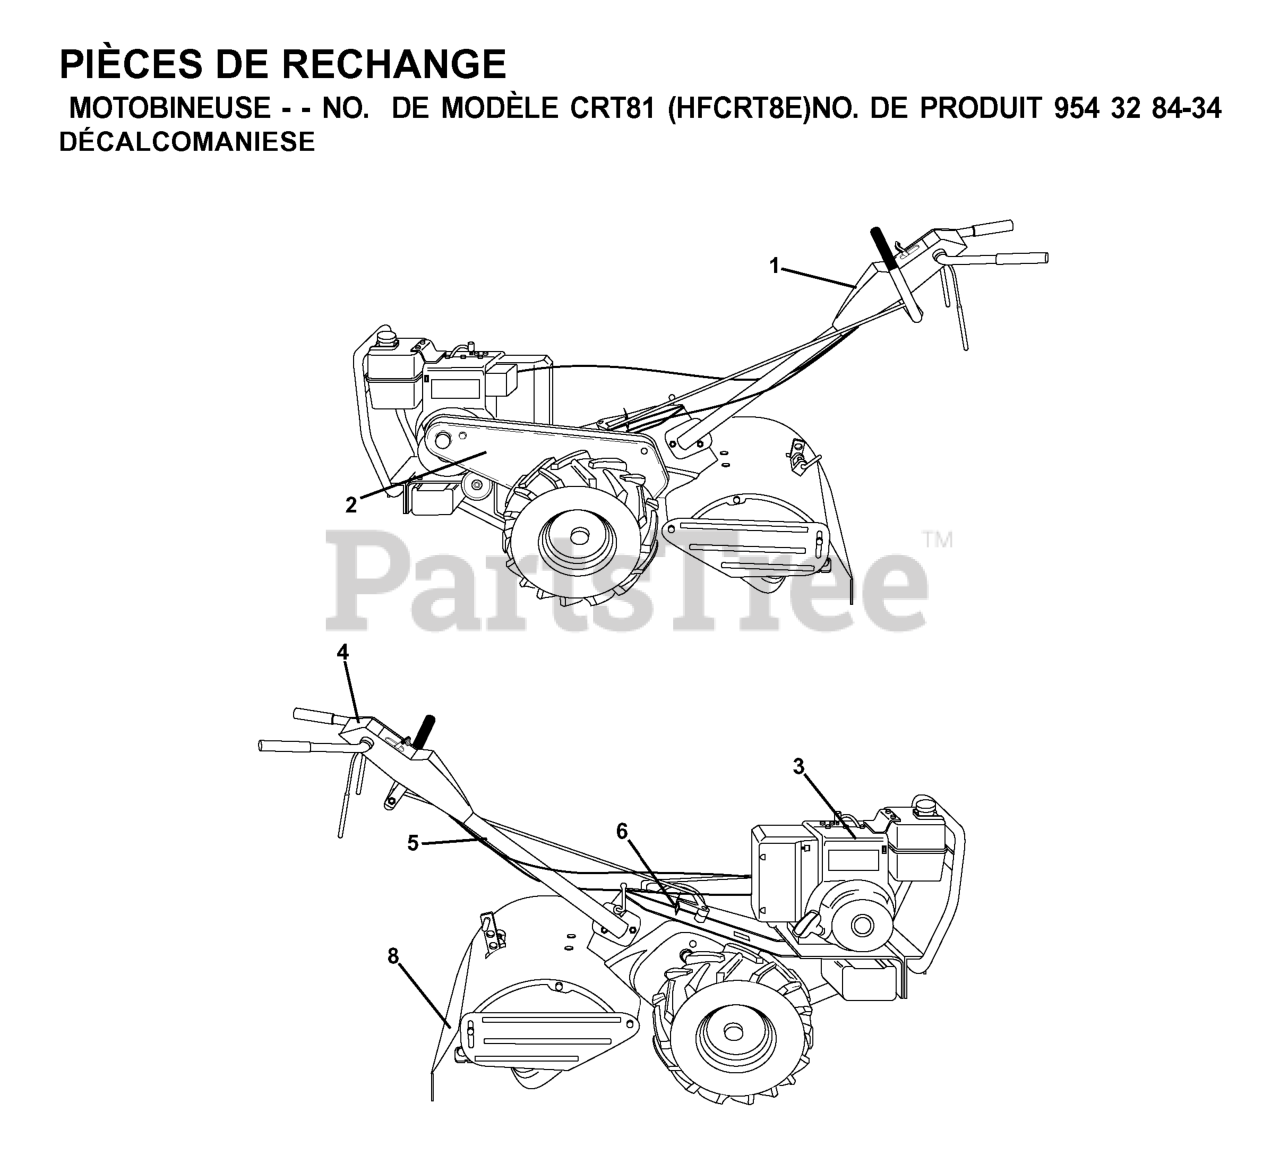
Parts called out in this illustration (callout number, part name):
1	DECAL, LOGO
3	DECAL EUROPE STANDARD CE
4	DECAL INSTRUCTION
5	DECAL.PLACEMENT.HAND.SYMBOLS
6	DECAL, SHIFT INDICATOR
8	DECAL.WARNING.4-SYM.TILLER.INT
